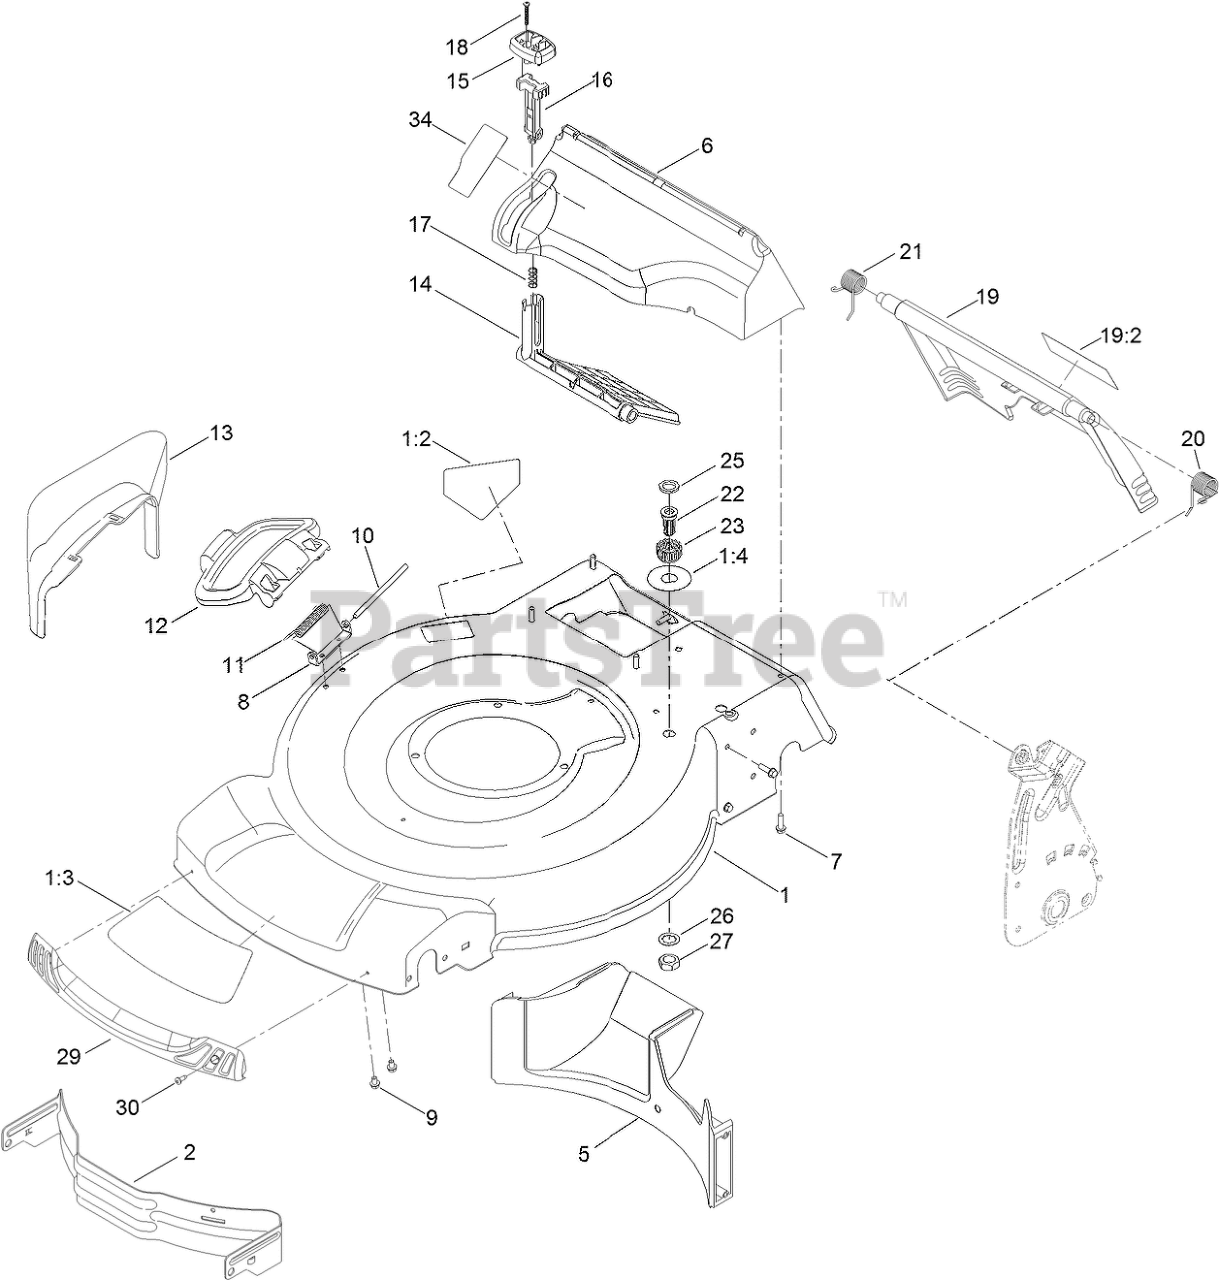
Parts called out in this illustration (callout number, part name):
1	HOUSING ASM
1:2	DECAL-DANGER
1:3	DECAL-RECYCLER
1:4	DECAL-PORT, WASHOUT
2	BAFFLE-FRONT
5	BAFFLE-REAR
6	CHUTE-RECYCLE
7	SCREW-HWH
8	BRACKET-COVER
9	SCREW-HWH
10	ROD-COVER
11	SPRING-TORSION
12	DEFLECTOR-SIDE
13	CHUTE-DISCHARGE, SIDE
14	DEFLECTOR-RECYCLE
15	KNOB-RECYCLE
16	LATCH-RECYCLE
17	SPRING-COMPRESSION
18	SCREW-PPH
19	REAR DOOR ASM
19:2	DECAL-WARNING
20	SPRING-TORSION
21	SPRING-TORSION
22	PORT-WASHOUT
23	COUPLING-HOSE, WASHOUT PORT
25	WASHER-SEAL, WASHOUT PORT
26	WASHER-TOOTH, INTERNAL
27	NUT-JAM
29	BUMPER
30	SCREW-FORMING, THREAD
